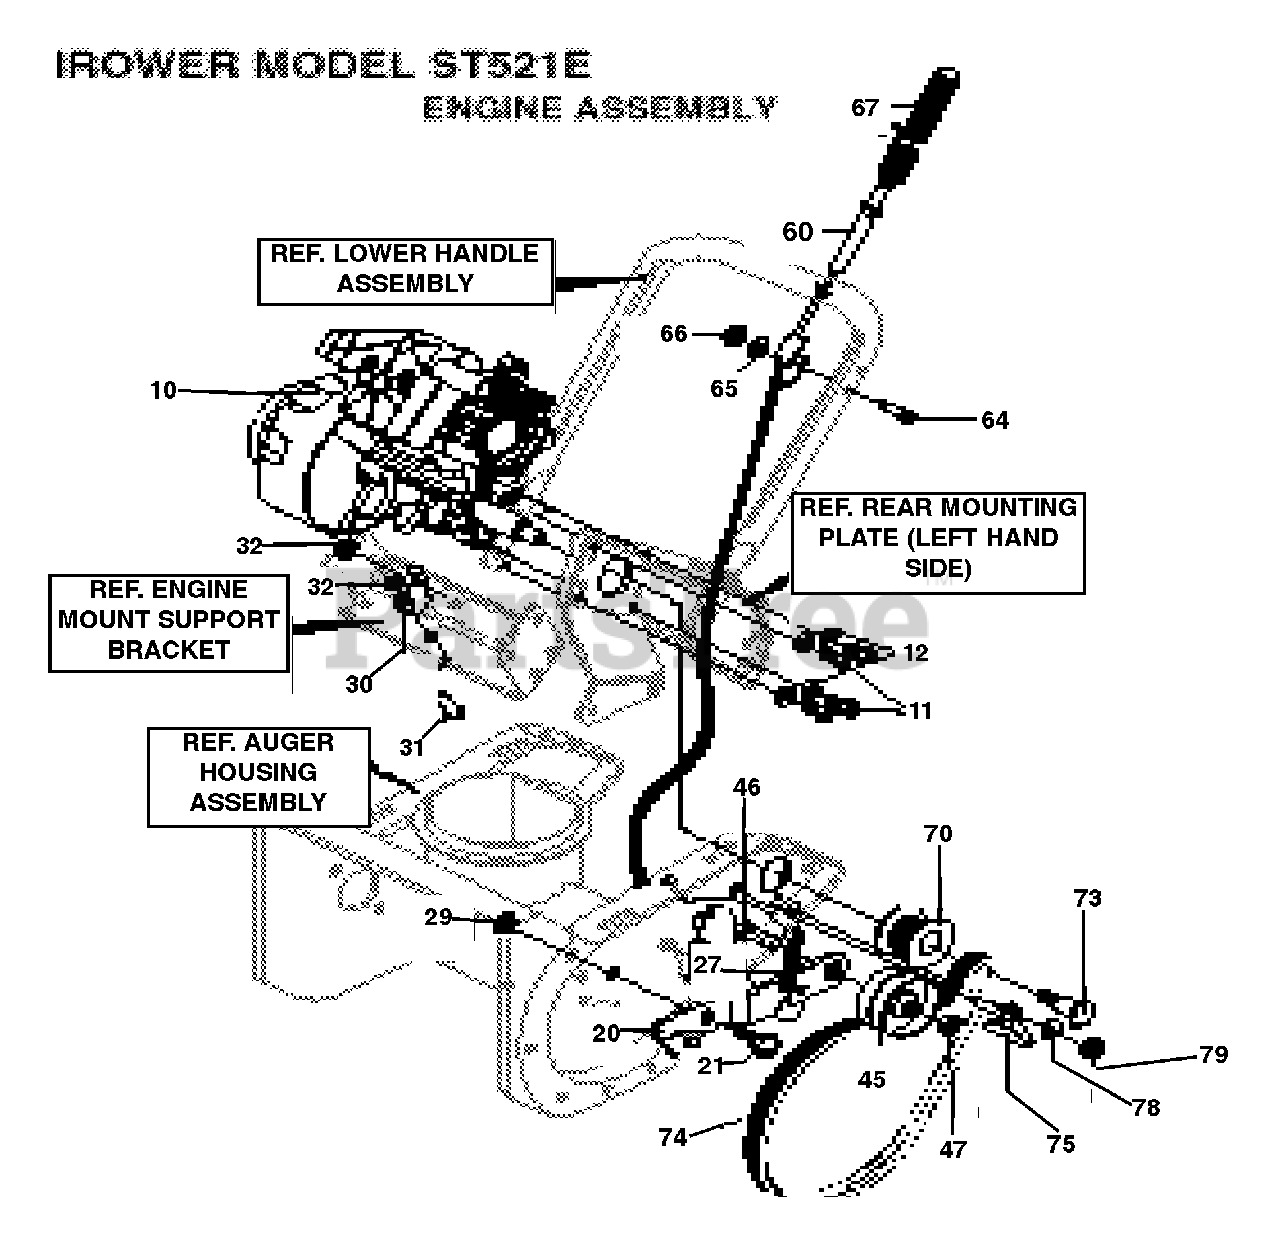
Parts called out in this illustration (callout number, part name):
10	ENGINE 5.0 HP
11	SCREW, 5/16-18 X .75
20	BRKT, IDLER ARM
21	BOLT, .5/16-18
27	SPRING, IDLER BRAKE
29	NUT, 5/16-18 REGHEXCTRLK
30	SUPPORT, ENGINE
31	SCREW, 5/16-18 X .50
32	NUT, 5/16-18 REGHEXCTRLK
45	PULLEY, IDLER
46	BOLT, 3/8-16 X 1.50
47	NUT, 3/8-16 HXCTRLKJAM
60	CABLE, DRIVE CONTROL
64	SCREW, 1/4-20 X 1.50
65	WASHER, FLAT .281 X .63 X .065
66	NUT, 1/4-20 REGHEXCTRLK
67	COVER, CABLE SPRING
70	PULLEY, 10-RIB POLY-V
73	BOLT, SHOULDER .625 X .282
74	BELT, 10 RIB POLY-V
75	GUIDE, BELT
78	WASHER, FLAT .312 X .73 X.065
79	NUT, 5/16-18 REGHEXCTRLK
